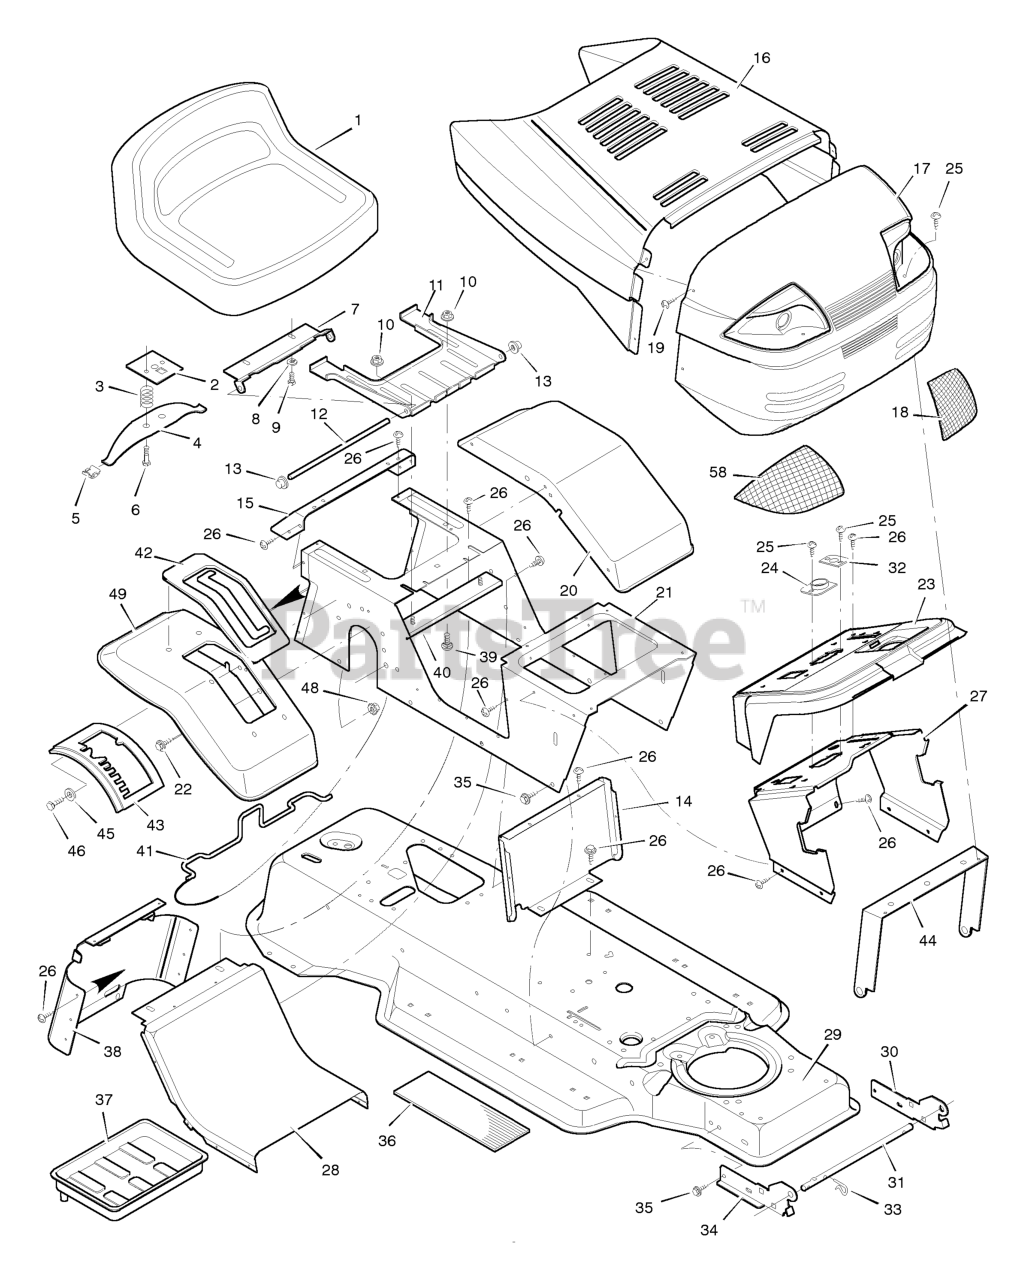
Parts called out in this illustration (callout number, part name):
2	Plate Assembly, Switch
3	Spring, Compression
4	Spring, Seat
5	Glide, Spring
6	Bolt, Shoulder
7	Support, Seat
8	Lockwasher
9	Bolt, Hex
10	Locknut, Flange
11	Bracket, Pivot
12	Rod, Pivot
13	Cap, Push On
14	Insert, Front
15	Fender, Apron
16	Hood
17	Grille Assembly
18	Lens, Left
21	Console Assembly
23	Dash Panel
24	Bearing, Steering
26	Screw
27	Support, Dash
28	Insert, Rear
29	Frame Assembly
30	Bracket, Left Grille
31	Rod, Pivot
32	Bearing
33	Pin, Hair
34	Bracket, Right Grille
37	Tray, Battery
38	Cap, Console
39	Bolt
40	Channel Assembly
41	Clamp, Battery
42	Cover, Shift
43	Gate, Shift
44	Brace, Grille
45	Washer
46	Bolt, Hex
48	Locknut
49	Fender, SOG
58	Lens, Right
